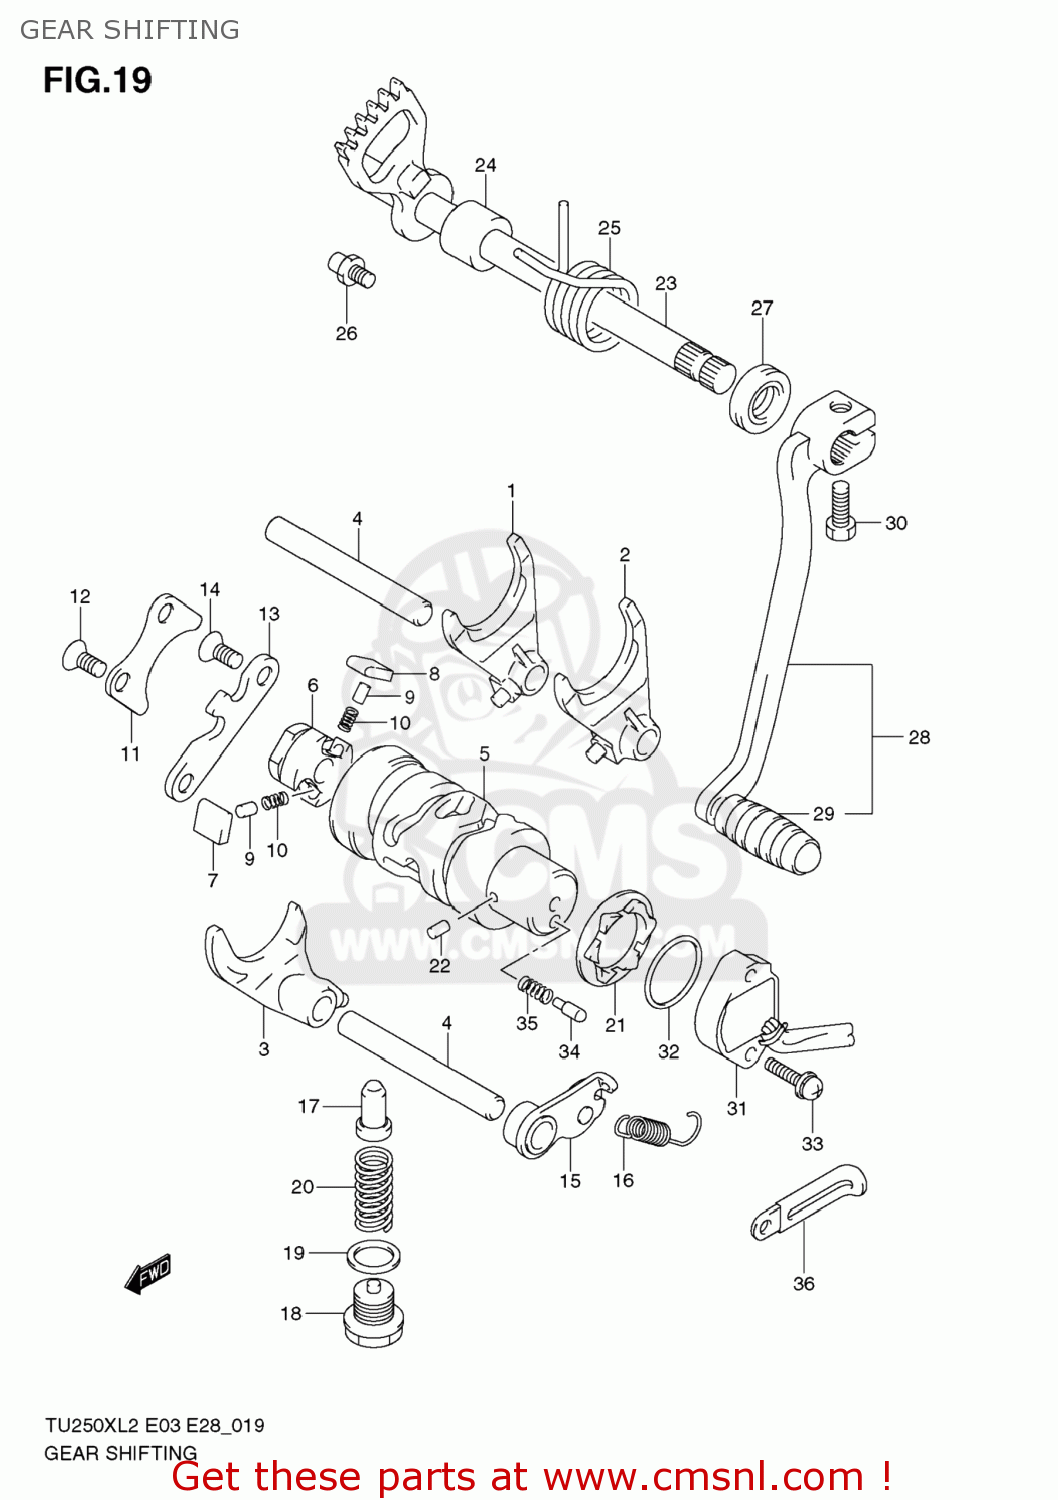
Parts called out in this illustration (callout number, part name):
1	FORK,GEAR SHIFT NO.1
2	FORK,GEAR SHIFT NO.2
3	FORK,GEAR SHIFT NO.3
4	SHAFT,GEAR SHIFT FORK
5	CAM,GEAR SHIFT
6	GEAR,GEAR SHIFT CAM DRIVEN
7	PAWL,GEAR SHIFT NO.1
8	PAWL,GEAR SHIFT NO.2
9	PIN(5X8)
10	SPRING
11	LIFTER,GEAR SHIFT POLE
12	SCREW(6X12)
13	GUIDE,GEAR SHIFT CAM
14	SCREW(6X12)
15	STOPPER,GEAR SHIFT CAM
16	SPRING
17	STOPPER,GEAR SHIFT CAM NO.2
18	PLUG(14X12)
19	GASKET(13.8X18.8X4.8) (NAS)
20	SPRING
21	PLATE,GEAR SHIFT CAM STOPPER
22	PIN
23	SHAFT,GEAR SHIFT
24	SPACER(12X20X15.3)
25	SPRING
26	STOPPER,GEAR SHIFT ARM
27	SEAL,OIL (12X22X9)
28	LEVER ASSY,GEAR SHIFT
29	RUBBER,GEAR SHIFT PEDAL
30	BOLT
31	BASE ASSY,GEAR SHIFT TERMINAL
32	O RING(D:2.4,ID:26.2)
33	BOLT(5X16)
34	PIN(5X15.5)
35	SPRING
36	CLAMP(L:80)
